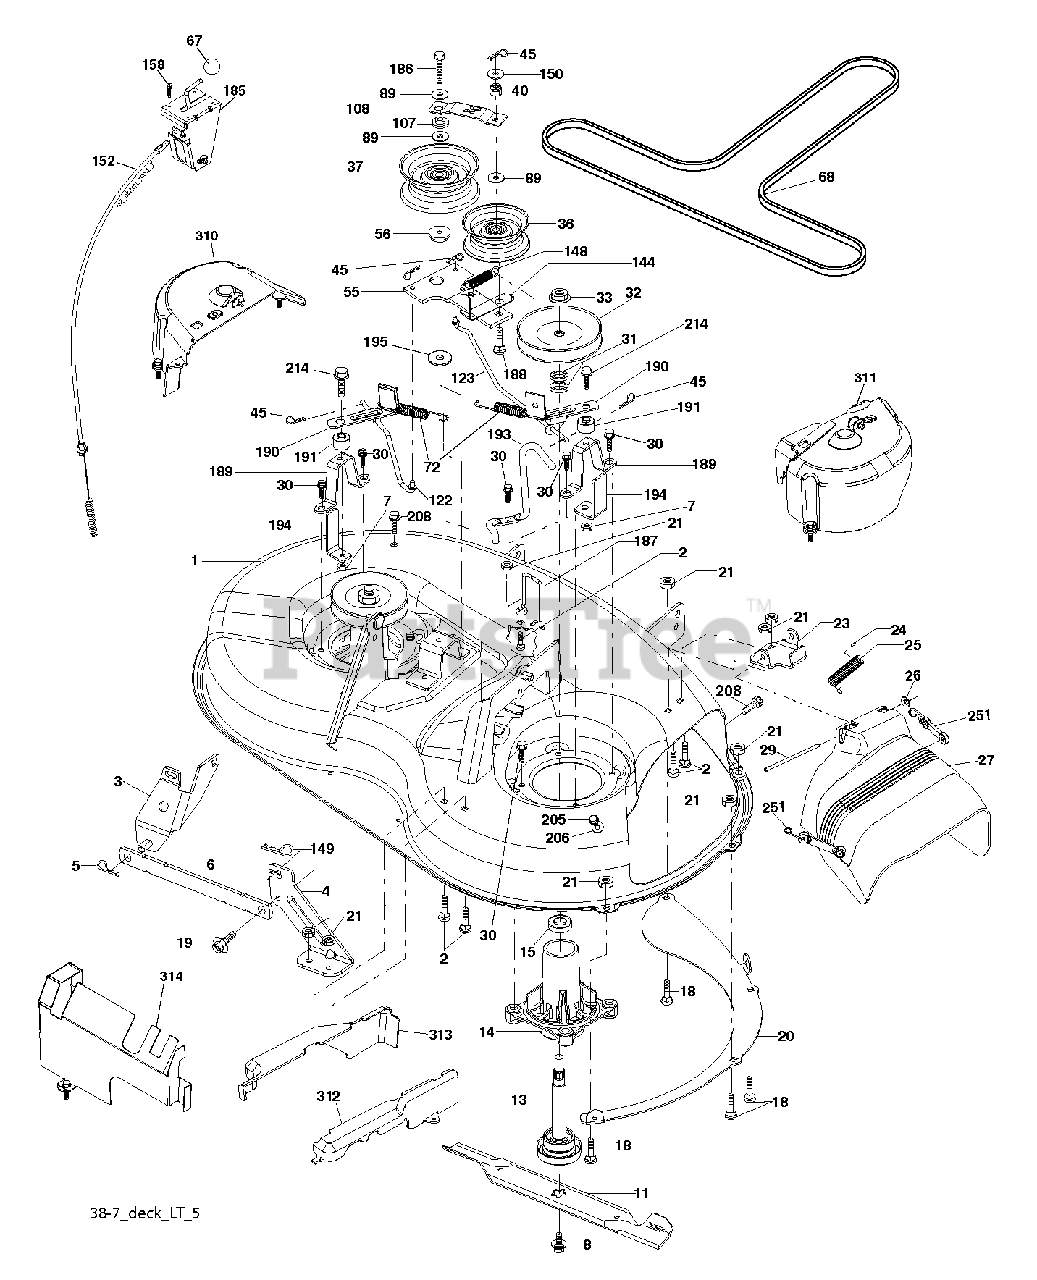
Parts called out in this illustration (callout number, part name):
1	DECK SVC 38/94 192556X431
2	BOLT 5/16-18 X3/4 ZN/YEL GR 5
3	BRKT ASM SWAY BAR
4	BRACKET DECK SWAY BAR 38"/42"
5	Retainer Spring
6	BAR SWAY DECK
7	NUT.71038.31-18.HEX.NYLOCK
8	BOLT.WASHER.ASM.7/16-2
11	BLADE 38" PREMIUM
13	SHAFT.ASM.MDRL.N/GREASE.38
14	HOUSING.MANDREL.4PT.
18	BOLT
19	BOLT SHD 5/16-18
20	BAFFLE.VORTEX.FRONT.38"
21	LOCKNUT
23	BRKT.DEFLECTOR.38"2005+
24	CAP-SLEEVE LT
25	SPRING.TORSION.DEFLECT
26	NUT PUSH M
27	SHIELD ASM.DFLCTR MWR.38-7"BLK
29	ROD.HINGE
30	SCREW, WASHER HEAD
31	WASHER.SPACER.MANDREL
32	PULLEY MANDREL
33	NUT.FLANGE.LOCK.TOP
36	FLAT IDLER PULLEY
37	PULLEY.IDLER.FLAT.UNPLATED
45	RETAINER M
56	SPACER.RETAINER.MOWER
67	KNOB T (3/8 HOLE)
68	V-BELT.MOWER.38"2005+
72	SPRING.BRAKE.RETURN.38"
89	WASHER
107	SPACER.IDLER.ARM
108	STIFFENER.IDLER.ARM
122	LINK.BRAKE.38"LEFT.2007
123	LINK.BRAKE.38"RIGHT
144	KEEPER BELT
148	IDLER RETURN SPRING
149	SPRING.RETAINER.YELLOW.ZINC
152	CABLE.CLUTCH.38".SERVICE
158	SCREW
185	HEAD ASM. CABLE CLUTCH
186	SCREW.HXWSH.3/8
187	KEEPER BELT
188	BOLT, CARRIAGE IDLER
189	STAND, BRAKE
190	ARM, BRAKE
191	BRAKE.SPACER.38".DECK
193	KEEPER BELT RH MANDREL
194	GUARD BRAKE
195	WASHER 12/32X2X10GA
205	SCREW
208	SCREW 3/8-16X1/2
214	BOLT/WASHER ASM 5/16-18
251	ELASTIC STRAP KIT
